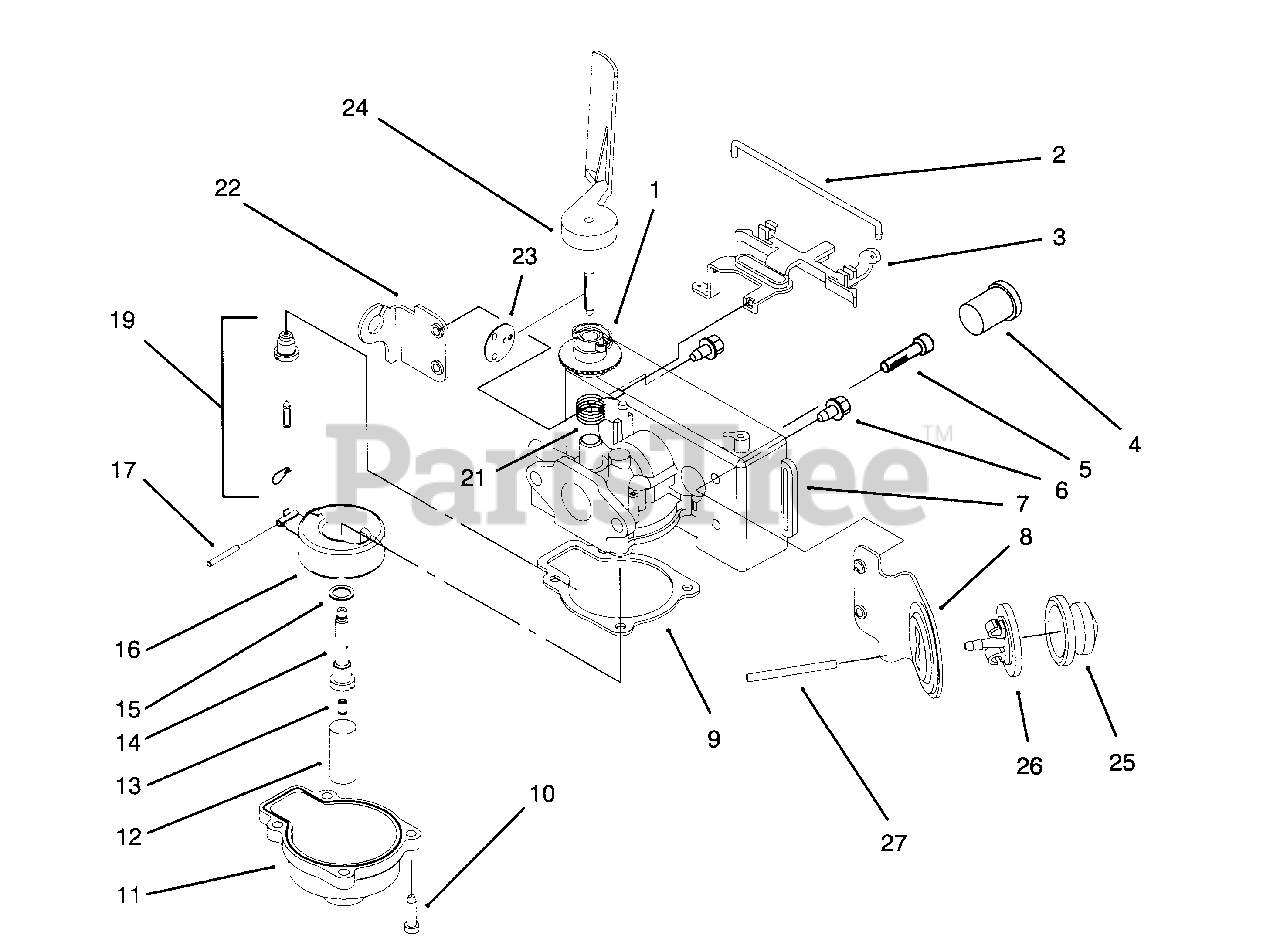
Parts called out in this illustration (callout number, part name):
1	Collar-Adjustment
2	Retainer
3	Lever-Speed Adjust
4	Plug
5	Screw-Pan Hd. Sems
7	Body-Carburetor
8	Bracket-Primer
9	Gasket-Float Chamber
11	Float Chamber
12	Filter-Fuel
13	Main Jet
16	Float & Arm Assembly
19	Float, Valve, & Seat Ass'y
21	Spring-Governor
22	Bracket-Throttle Control
23	Disc-Throttle
24	Air Vane & Shaft
25	Bulb-Primer
26	Body-Primer
27	Hose-Primer
